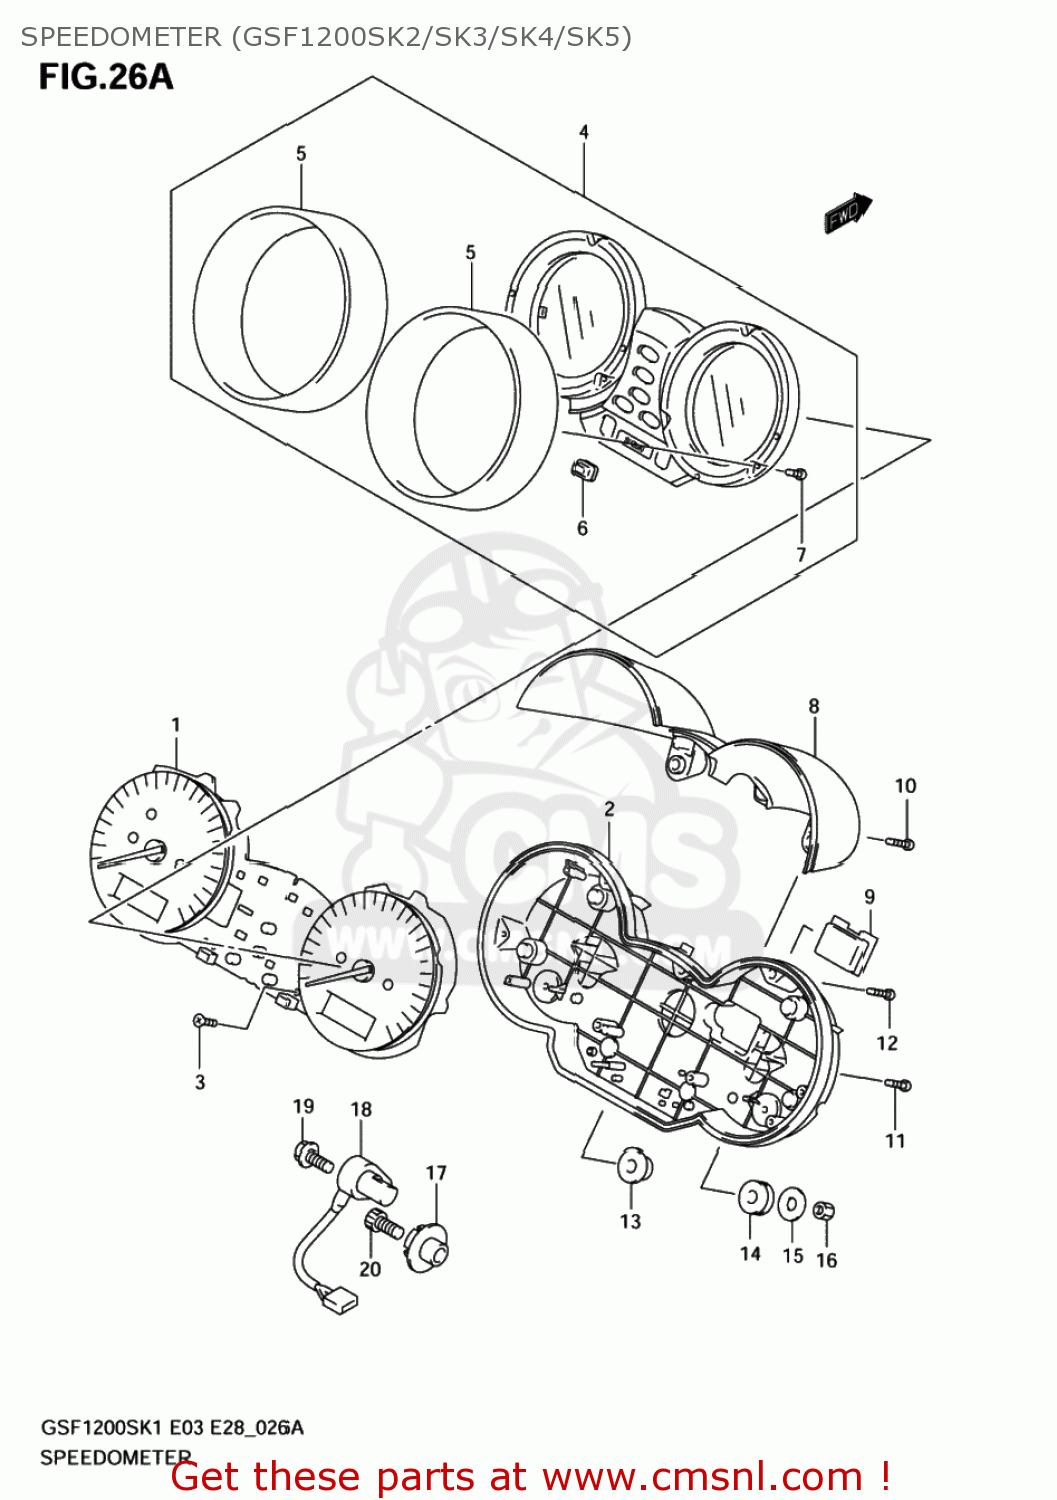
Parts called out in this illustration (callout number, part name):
1	SPEEDOMETER
2	CASE ASSY,LOWE
3	SCREW(4X14)
4	UPR CASE ASSY
5	RING
6	RUBBER,SWITCH
7	SCREW(2.3X8)
8	COVER
9	GROMMET
10	SCREW,PAN HEAD(3X14)
11	SCREW,PAN HEAD(3X16)
12	SCREW(3X16)
13	CUSHION
14	CUSHION
15	WASHER(5.5X16X1.2)
16	NUT
17	ROTOR,SPEED
18	SENSOR,SPEED
19	BOLT
20	BOLT
